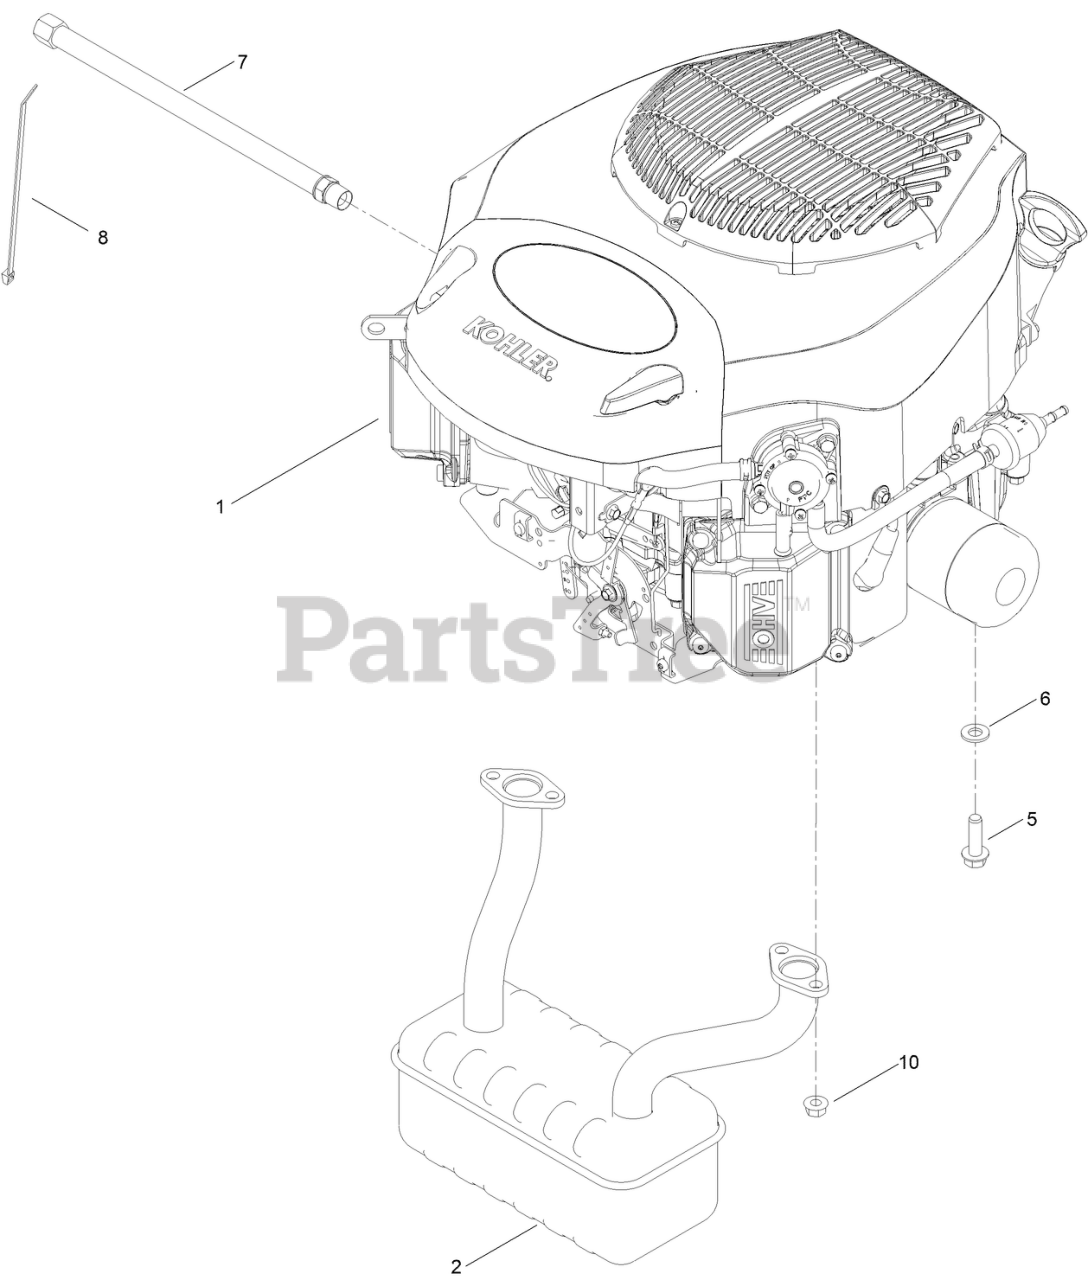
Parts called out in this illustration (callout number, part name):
1	ENGINE-KOHLER, KT725 LOW SPEED
2	MUFFLER
5	SCREW-HWH, THD ROLL
6	WASHER-FLAT
7	HOSE-DRAIN, OIL
8	TIE-CABLE
10	NUT-HF
